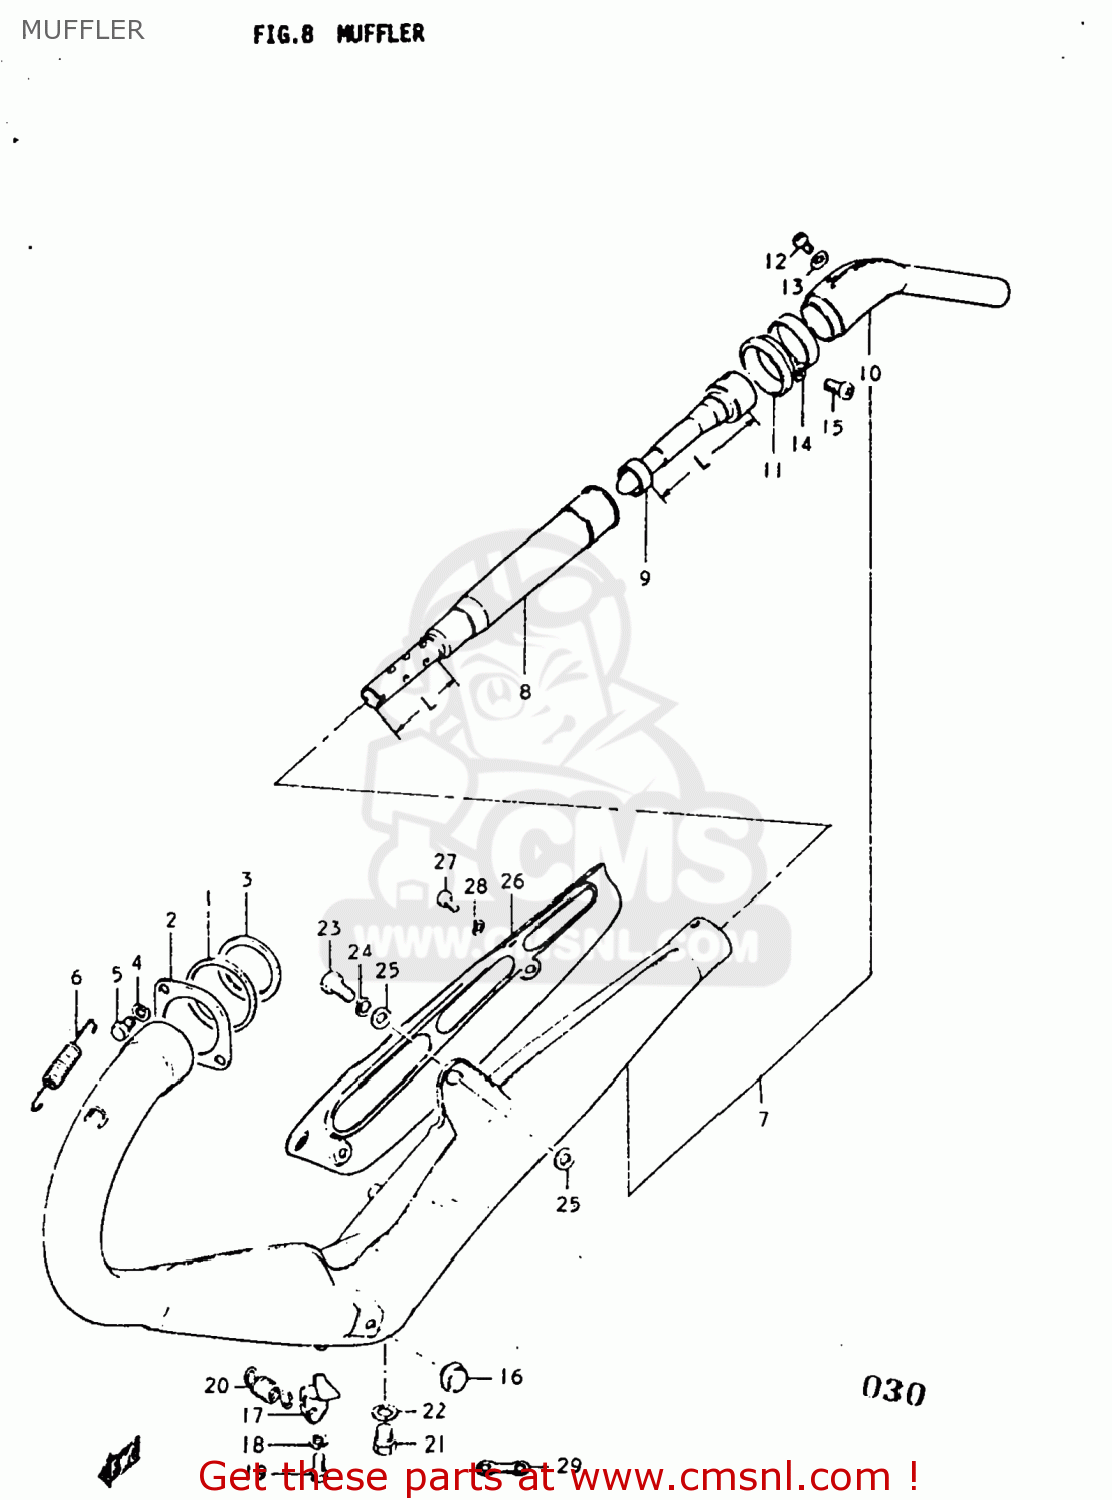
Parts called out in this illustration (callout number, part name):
1	GASKET,EXHAUST PIPE (NAS)
2	CLAMP,EXHAUST PIPE
3	CUSHION,EXHAUST PIPE
4	LOCK WASHER
5	BOLT
6	SPRING
7	MUFFLER ASSEMBLY
8	ARRESTER,SPARK
9	TUBE,MUFFLER CLEAN OUT
10	EXHAUST EXTENSION
11	GASKET,MUFFLER TAIL PIPE (NAS)
12	Screw
13	GASKET
14	CLAMP
15	SCREW
16	CUSHION(11.5X22X20)
17	BRACKET, MUFFLER STOPPER
18	LOCK WASHER
19	BOLT
20	SPRING
21	BOLT 10X9
22	GASKET(10X14X3.6) (NAS)
23	BOLT
24	LOCK WASHER
25	WASHER
26	COVER,MUFFLER
27	SCREW
28	LOCK WASHER
29	CLAMP
